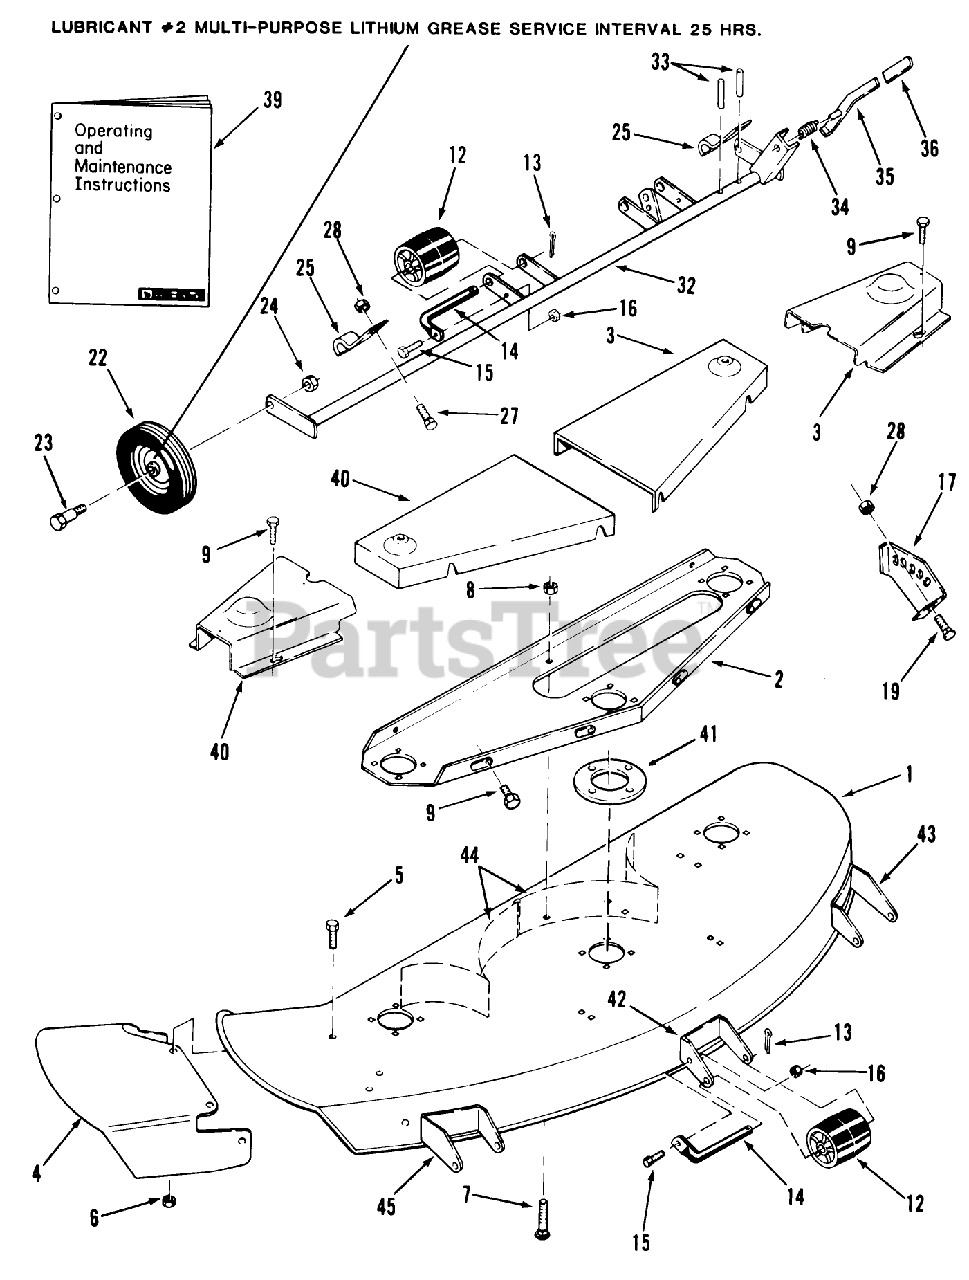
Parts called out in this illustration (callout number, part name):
9	Bolt
14	ROLLER-SHAFT
22	WHEEL
23	BOLT-SHOULDER
33	PIN-SPIROL
34	SPRING-COMPRESSION
41	PLATE-SPINDLE
43	BRKT-ROLLER
44	BAFFLE-DECK L.H.
44	BAFFLE-DECK R.H.
44	BAFFLE-DECK RH
